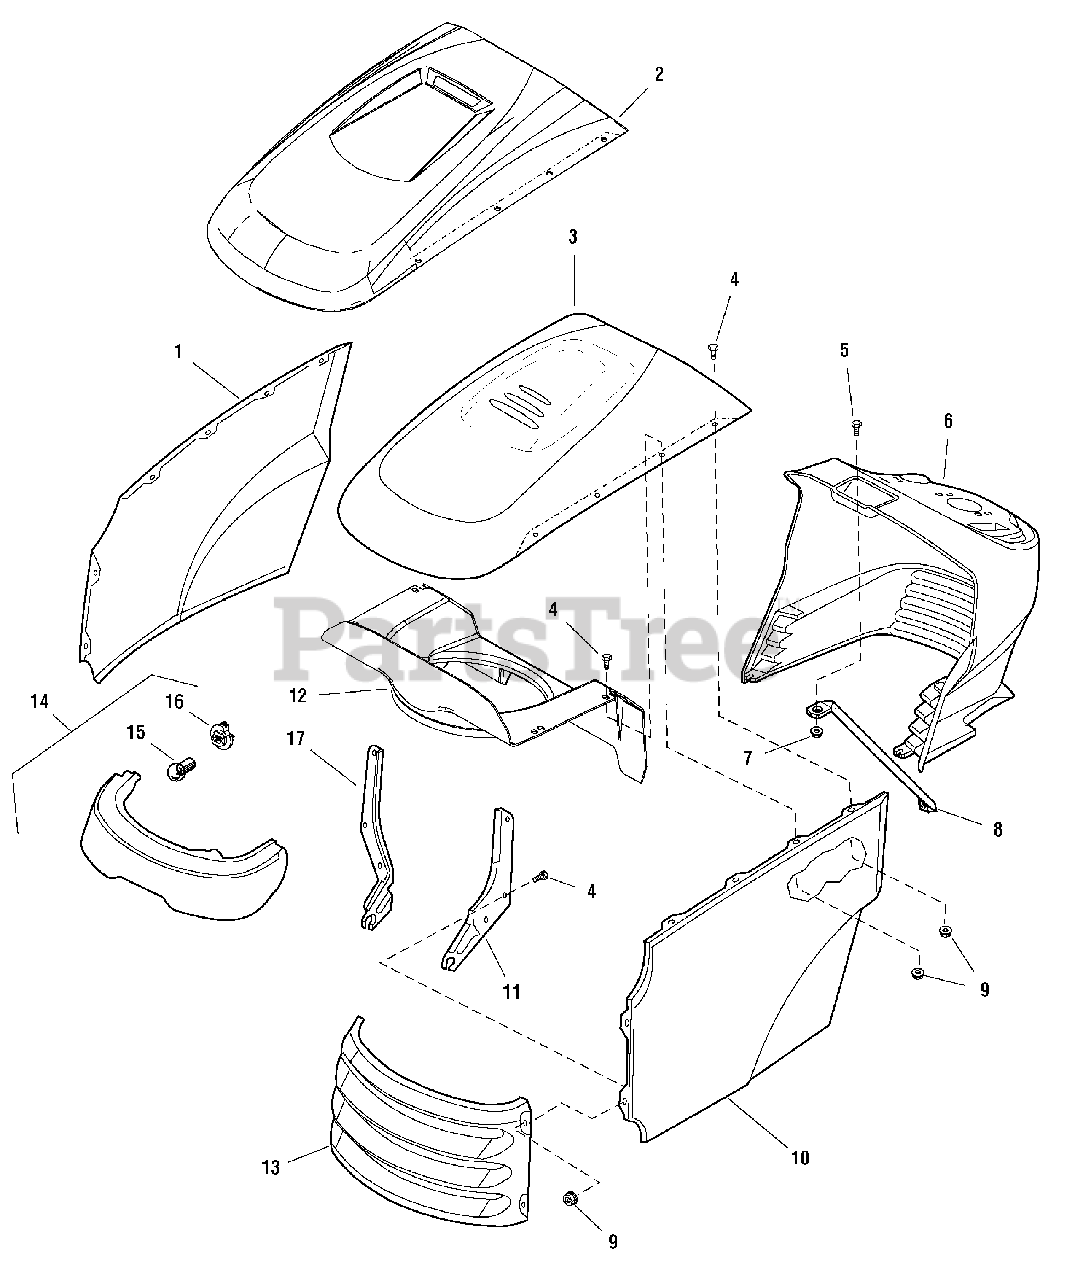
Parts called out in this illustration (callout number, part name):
1	PANEL, RH Side, Orange
1	PANEL, RH Side, Red
2	HOOD, with Scoop, Red
3	HOOD, with Louvers, Orange
3	HOOD, with Louvers, Red
4	CAPSCREW, Hex Head Flange Lock,1/4-20 x 5/8
5	SCREW, Phillips Head, #10-24 x 1/2
6	DASHBOARD, RMO, Black
6	DASHBOARD, RMO with Hydra Lift Slot, Black
7	NUT, Hex Nylock,#10-24
8	ROD, Dash Support
9	NUT, Hex Flange Lock, 1/4-20
10	PANEL, LH Side, Orange
10	PANEL, LH Side, Red
11	HINGE, LH
12	DUCT, Air Inlet
13	GRILLE, Orange
13	GRILLE, Red
14	HEADLIGHT ASSEMBLY
15	BULB, Headlight
16	SOCKET, Headlight
17	HINGE, RH
